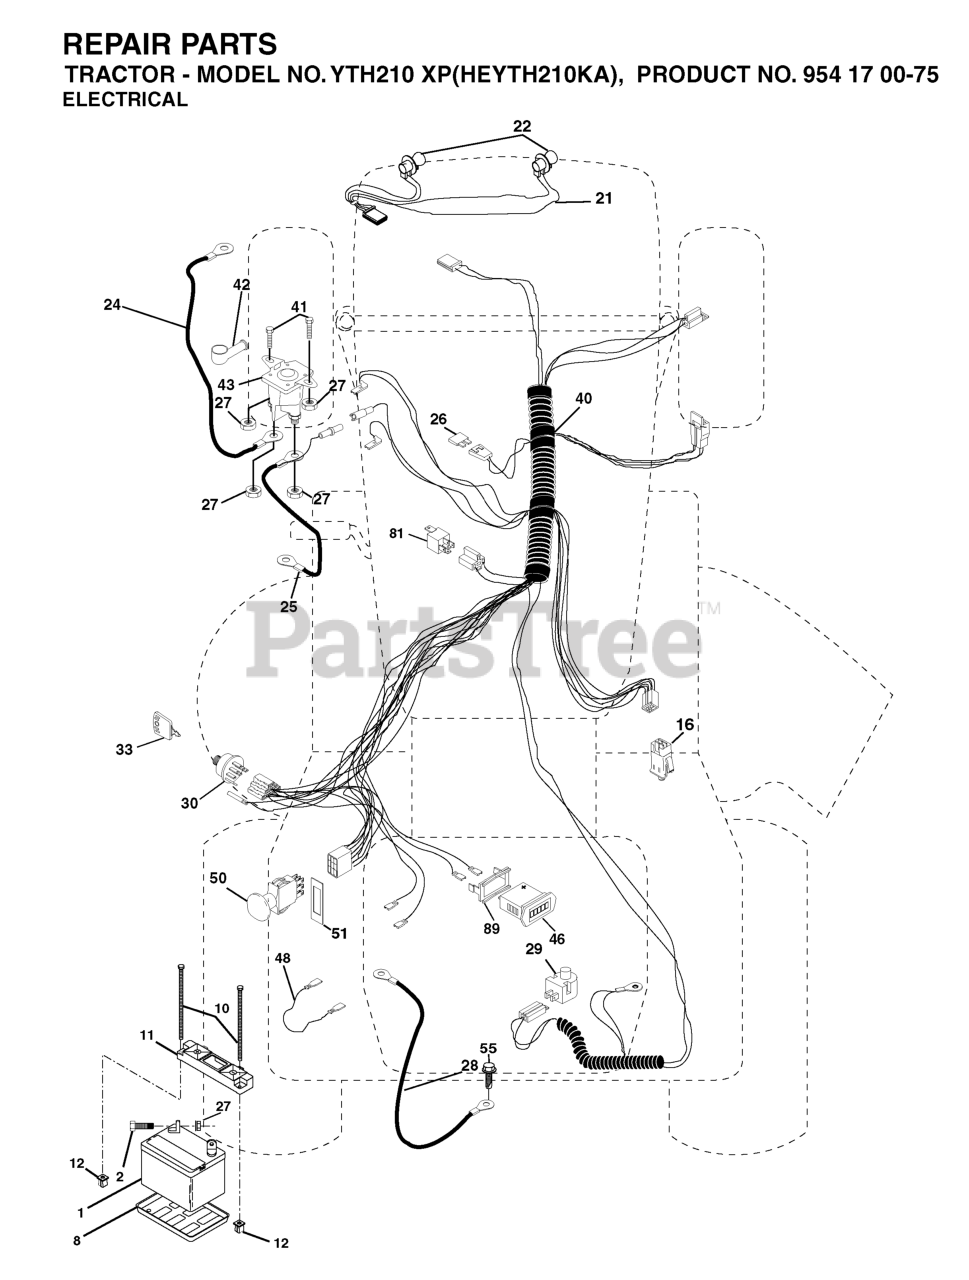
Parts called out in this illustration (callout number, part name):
1	BATTERY 12V .35 AMP
2	BOLT.HEX.1/4.X.3/4.DICHROMATE
8	BATTERY TRAY T
10	BOLT 1/4-20 X 7.5
11	BATTERY HOLDDOWN FRONT MOUNT
12	NUT, PUSH NYLON 1/4" BATTERY
16	SWITCH INTERLOOK PUSH-IN
21	HARNESS.W/LIGHT SOCKET
24	BATTERY CABLE GT
25	CABLE BATTERY 6 GA 22" W/16W
26	FUSE 20AMP
27	NUT
28	CABLE GROUND 6 GA 21" 90T BLK
29	PLUNGER SWITCH (COLOR:OLIVE)
30	IGNITION SWITCH
33	KEY MLD GEN DELTA
40	HARNESS IGN.
41	BOLT
42	TERMINAL COVER
43	SOLENOID
46	HOUR METER
48	ADAPTER.AMMETER
50	RP.PTO.SWITCH.8 TERMINAL.BLACK
51	FRAME RETAINING RING
55	Screw 5/16-18 x 1/2 Hex, Self Tapping 5/16-18 x 1/2
81	RELAY.ASSY.T
89	BRACKET SNAP-IN HOURMETER
